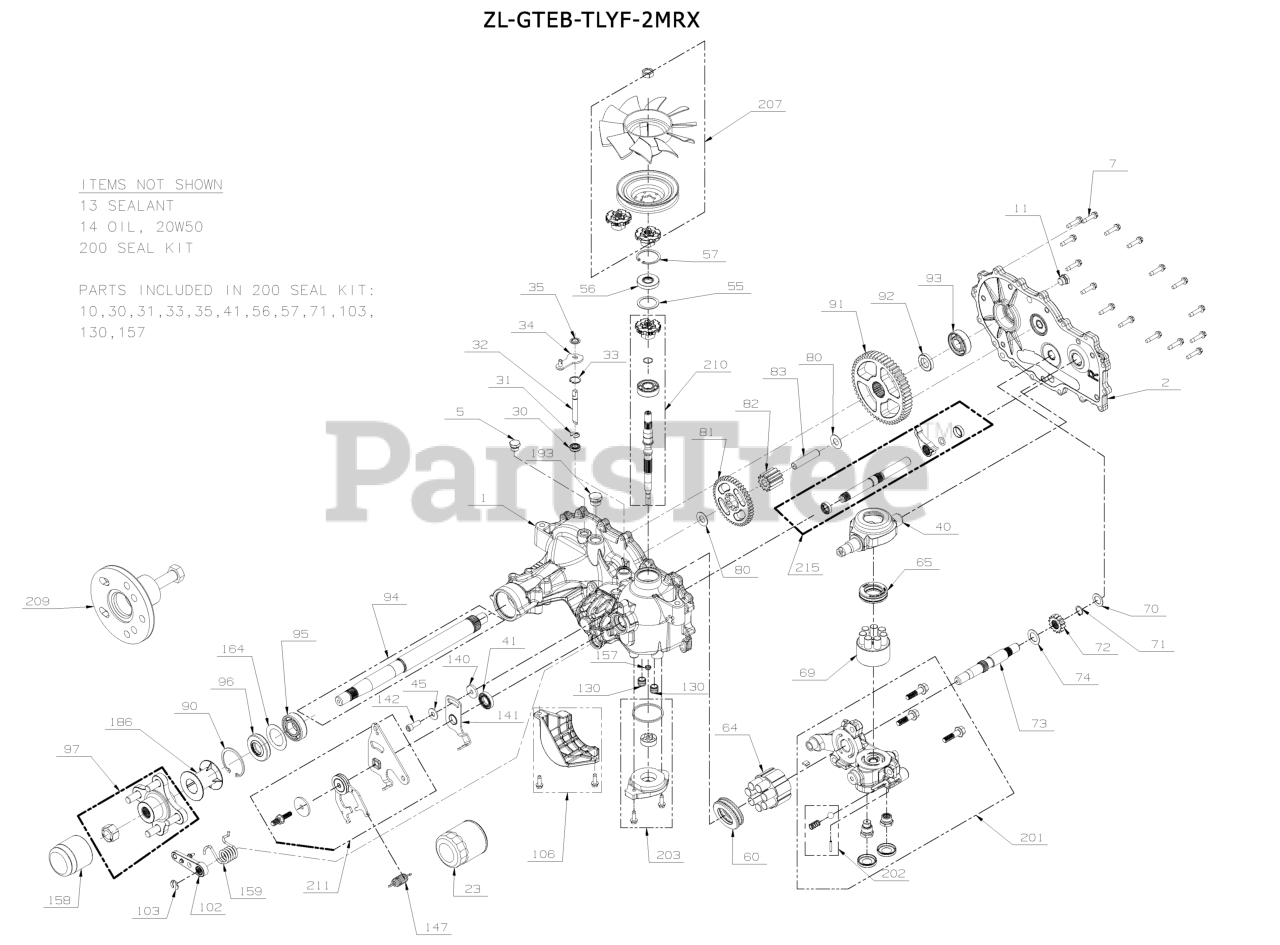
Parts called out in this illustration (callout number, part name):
1	KIT, HOUSING, MAIN RH, CNTRL, CHRG
2	KIT, SIDE COVER, RH
5	PLUG EXT HEX VENT 9/16 18
7	SCREW,HEX WASHER 1/4-20X1.125
11	PLUG EXT HEX VENT 9/16 18
13	SEALANT TUBE 10.1OZ.
14	FLUID, HYDRO 20W50 QT
14	FLUID, HYDRO 15W50 QT
23	FILTER, HYDRO-GEAR 2800 TRANS
30	Seal, lip .375 x 375 x 325
31	RING. RETAINING
32	ROD, BYPASS
33	RING, RET .750
34	ARM, BYPASS
35	RING, RTNG .
40	TRUNNION, SWASHPLATE
41	SEAL, LIP 18X32X7
55	WASHER 1.23X1.56X.04
56	SEAL, LIP 17X40X7
57	RING, RET 1.56 INT
60	HG THRUST BEARING (51462)
64	HG 16CC CYLINDER BLOCK (71579)
65	BEARING. THRUST 30 X 52 X 13
69	ASSY, BLOCK 7 PISTON
70	WASHER .63X1.0X.05
71	RING, RET 62 EXT
72	GEAR 14T STEEL
73	SHAFT, MOTOR
74	WASHER .71 X 1.16 X .04
80	WASHER .5X1.0X.032
81	GEAR 45 TOOTH
82	GEAR 11 TOOTH STEEL
83	JACK SHAFT (PIN)
90	RING, RETAINING
91	GEAR, 54T
92	SPACER
93	KIT, BEARING
94	SHAFT, AXLE
95	BEARING, BALL 25.4 X 52 X 15
96	SEAL, LIP
97	KIT, HUB 4 BOLT
102	BRAKE ARM HG 71957
103	CLIP,BRAKE ARM HYDROGEAR 52027
106	KIT FILTER GUARD
130	TUBE CHARGE TRIPLE ORING
141	ARM, NEUTRAL RIGHT
142	SHCS 5/16-24X1 PATCH
147	RTN SPRING HG 51605
157	KIT GEROTOR SEAL
158	CAP, AXLE
159	SPRING, TORSION CCW
164	WASHER, 1.355 x 2.035 x .021 FLAT
186	TUBE, AXLE 2.03
201	KIT, CENTER SECTION RH, CHARGE
202	KIT CHARGE RELIEF
203	KIT, CHARGE
207	KIT, FAN / PULLEY
209	HUB PULLER 5 BLT
210	KIT INPUT SHAFT
211	KIT, RTN, CW
215	KIT, OUTBOARD, RH ROT A / LH ROT B
